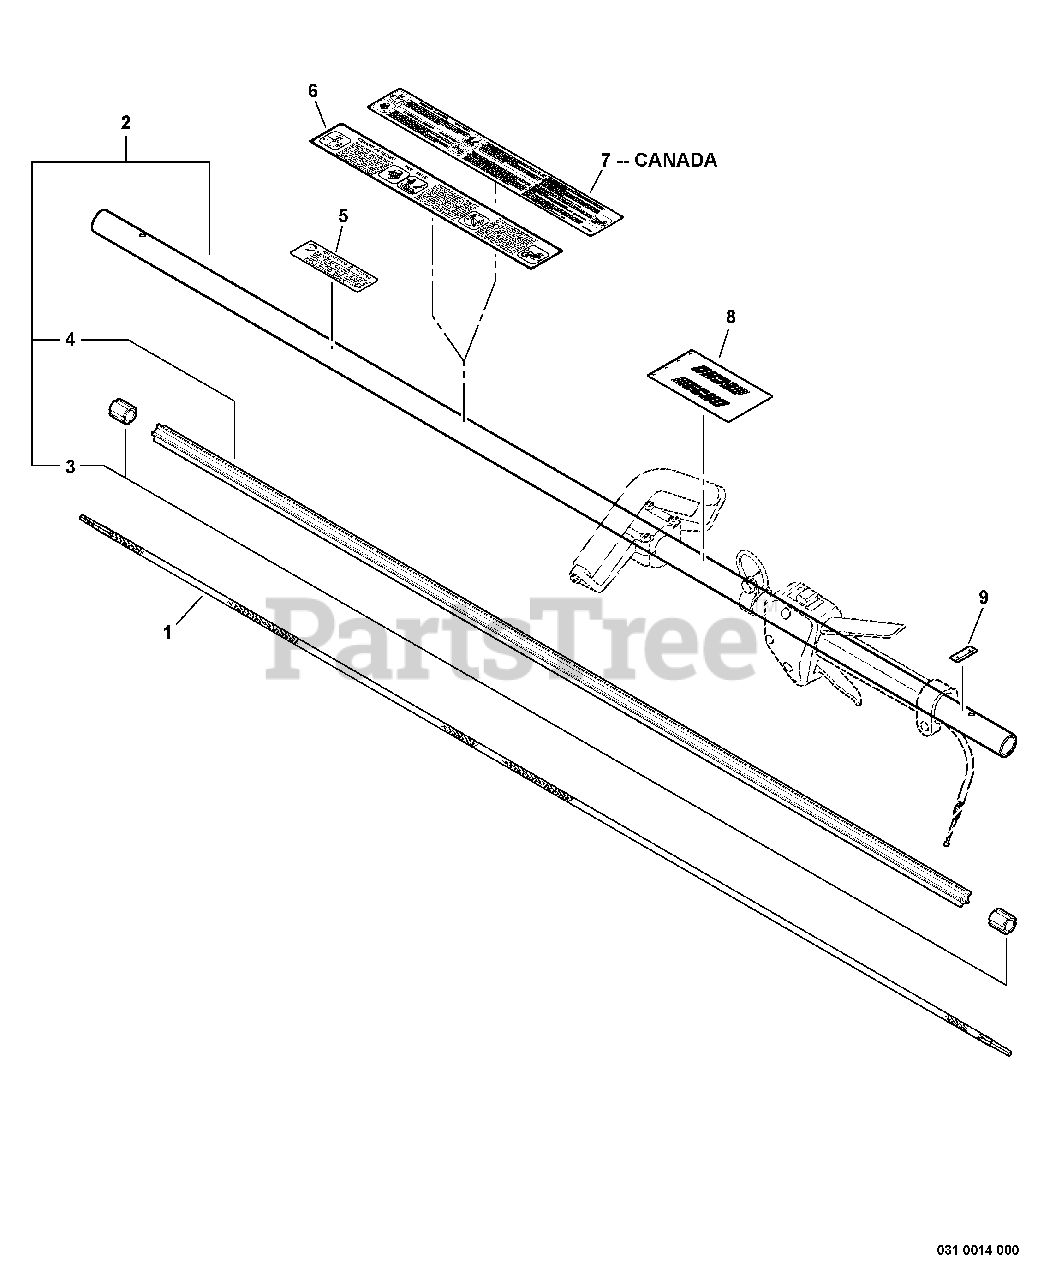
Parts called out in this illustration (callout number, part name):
1	DRIVESHAFT - FLEXIBLE L= 1522
2	MAIN PIPE ASSY
4	LINER, FLEXIBLE 21.6×1420
5	LABEL, CAUTION
6	LABEL, CAUTION
7	LABEL, CAUTION
8	LABEL, HANDLE LOCATION
9	LABEL - ALIGNMENT
